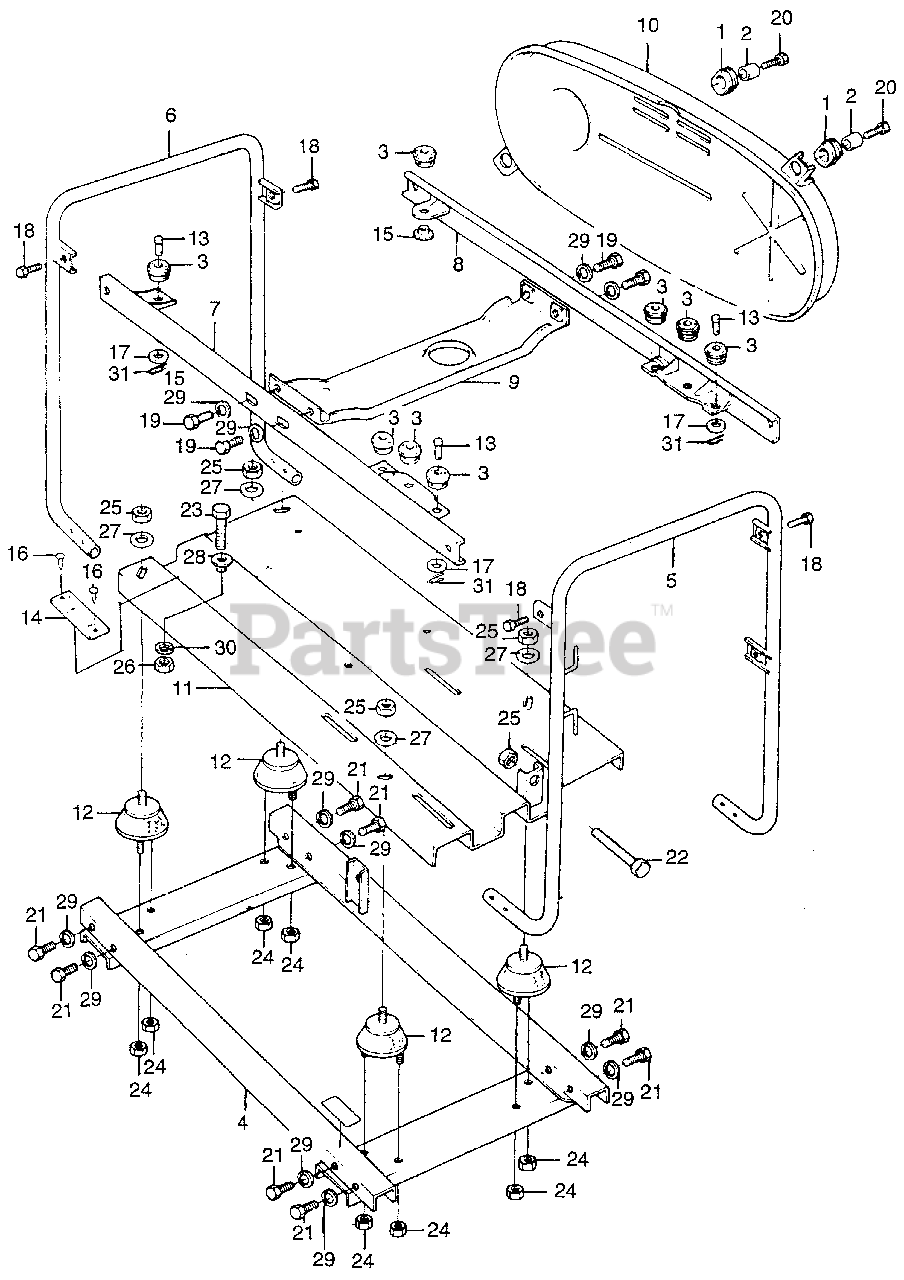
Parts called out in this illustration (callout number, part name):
1	RUBBER, TANK CUSHION (NOT AVAILABLE)
2	COLLAR, DISTANCE
3	RUBBER, TANK CUSHION
4	BED, FRAME (NOT AVAILABLE)
5	FRAME, R. SIDE
6	FRAME, L. SIDE
7	FRAME, FR. (UPPER)
8	FRAME, RR. (UPPER)
9	STOPPER, ENGINE
10	COVER, BELT *R8* (BRIGHT RED)
11	BED, ENGINE
12	RUBBER, ENGINE SETTING
13	PIN, CONTROL BOX SET (NOT AVAILABLE)
17	WASHER, FLAT (20MM)
18	BOLT, HEX. (8X16)
19	BOLT, HEX. (6X12)
20	BOLT-WASHER (6X20)
21	BOLT, HEX. (8X20)
22	BOLT, HEX. (8X50)
23	BOLT, HEX. (10X40)
24	NUT, HEX. (6MM)
25	NUT, HEX. (8MM)
26	NUT, HEX. (10MM)
27	WASHER, PLAIN (8MM)
28	WASHER, PLAIN (10MM)
29	WASHER, SPRING (8MM)
30	WASHER, SPRING (8MM)
31	PIN, LOCK (8MM)
